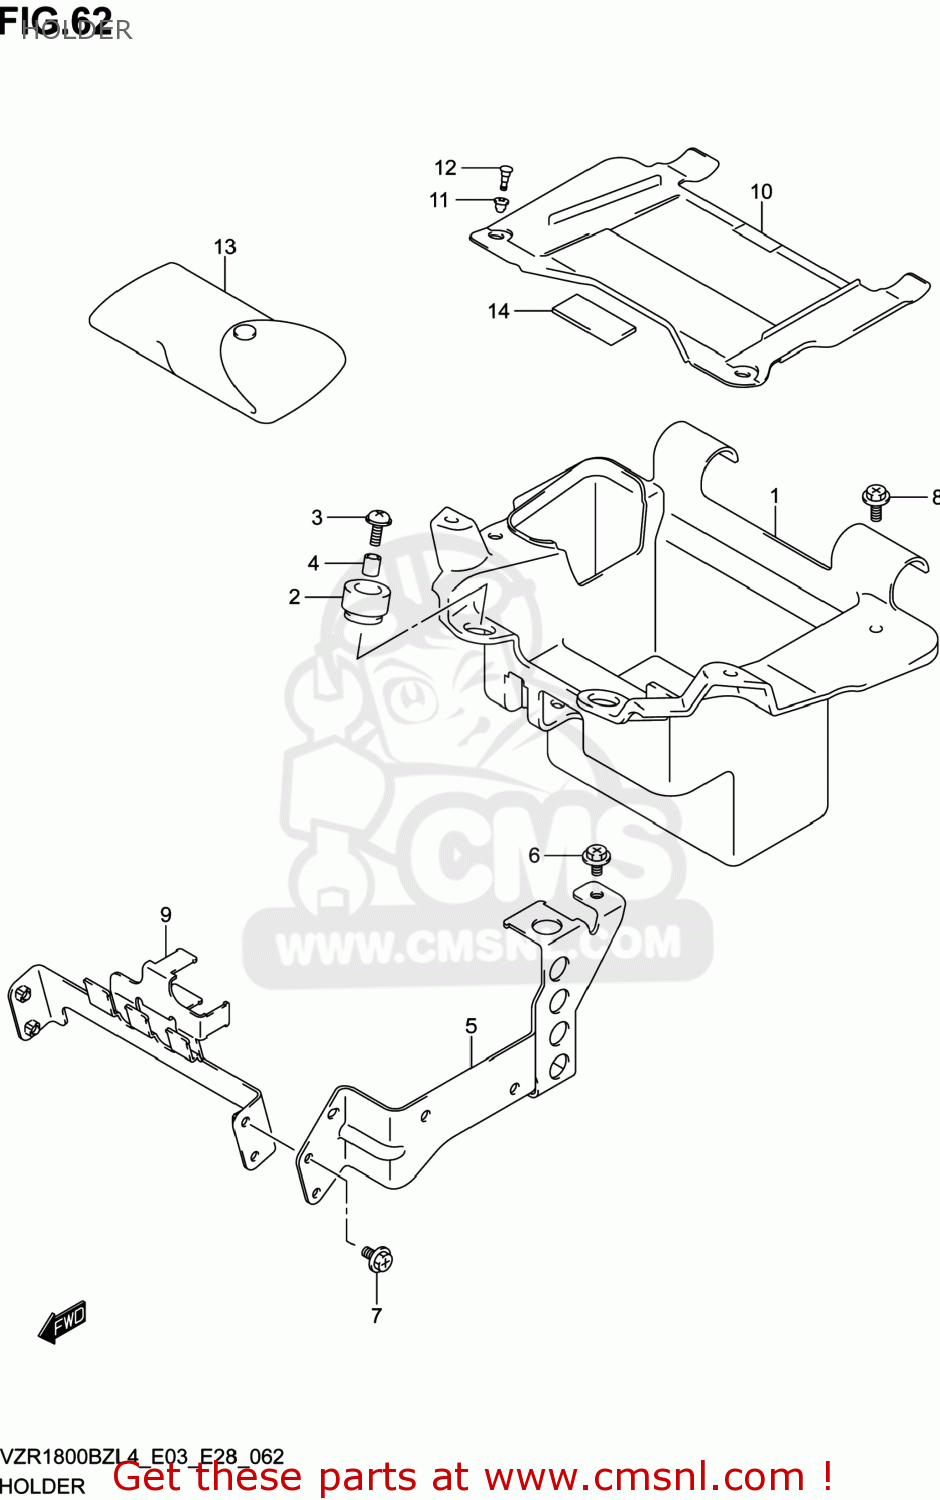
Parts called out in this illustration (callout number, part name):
1	HOLDER,BATTERY
2	CUSHION,SEAT TAIL COVER CTR
3	SCREW(6X20)
4	SPACER(6.5X10X11.5)
5	HOLDER,ELECTRIC PARTS
6	SCREW
7	SCREW
8	SCREW
9	BRACKET,RELAY
10	LID,BATTERY HOLDER
11	GROMMET
12	PLUNGER
13	TOOL ASSY
14	CUSHION,SEAT RAIL
